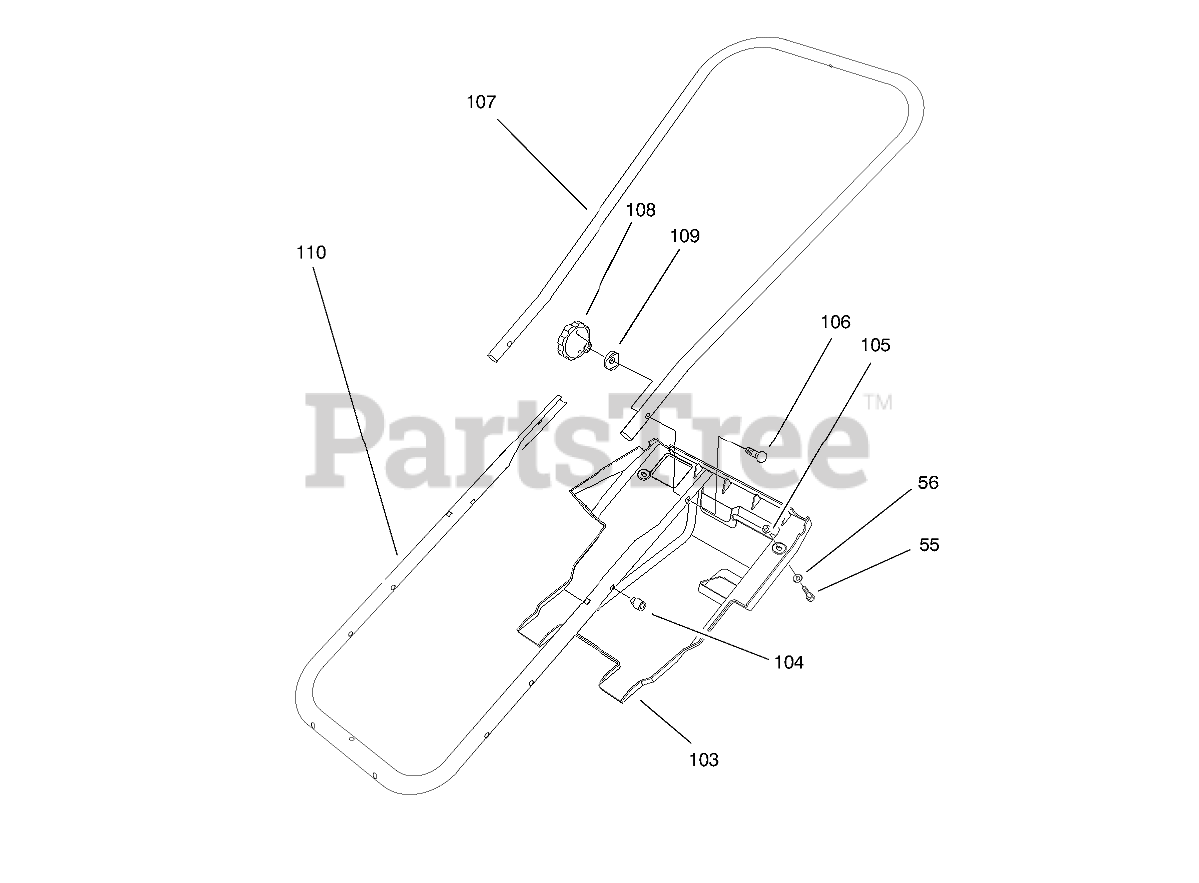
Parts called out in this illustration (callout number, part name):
55	SCREW-HWHTF
56	WASHER-FLAT
103	SHROUD
104	NUT-EXPANSION
105	NUT-CLIP
106	SCREW-HANDLE
107	Handle-Upper
109	WASHER-CURVED
110	Tube-Frame
